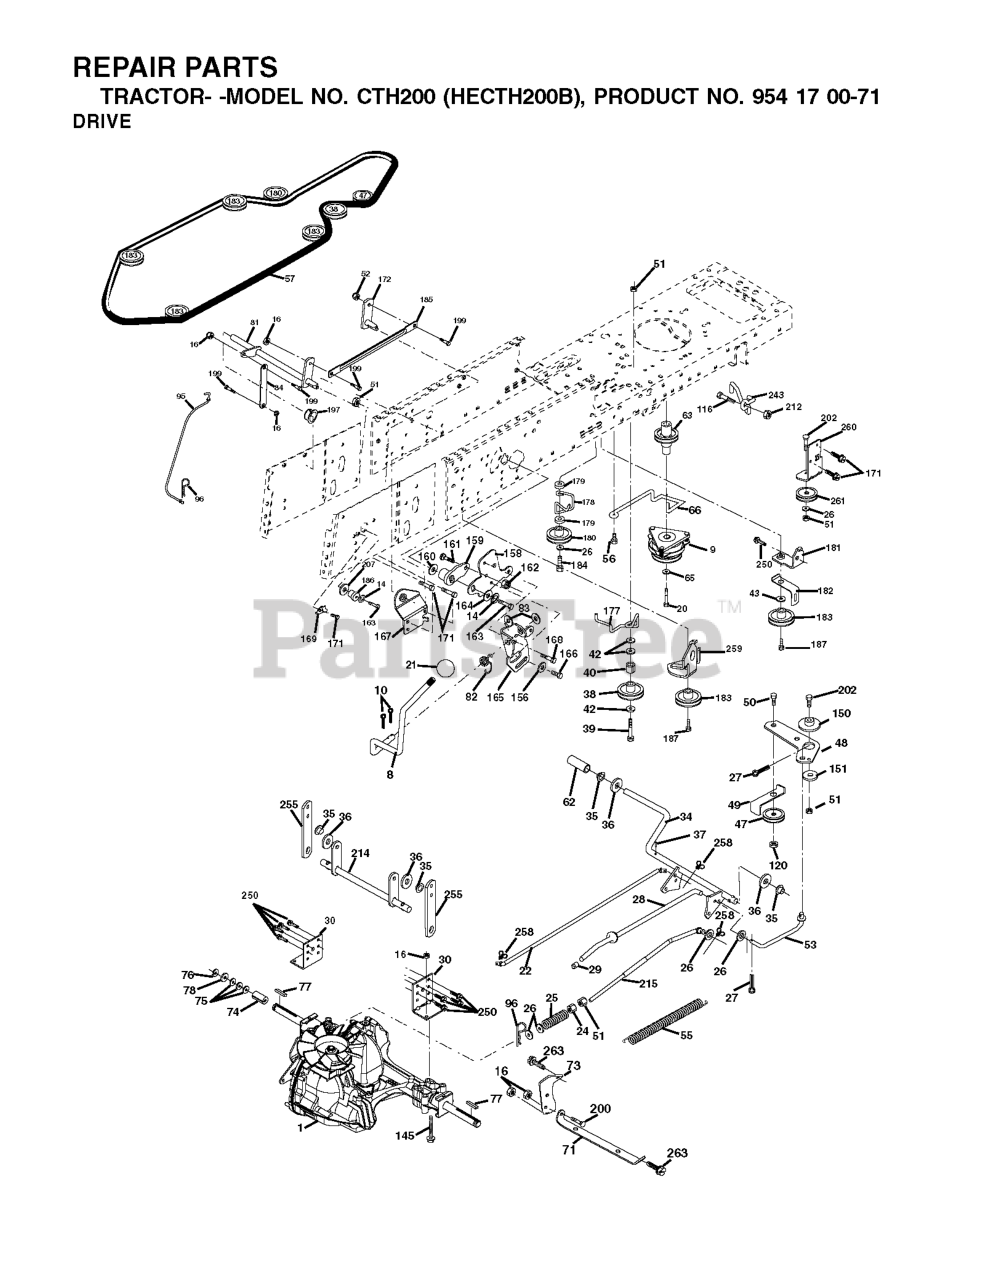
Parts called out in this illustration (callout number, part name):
8	ROD.SHIFT.FENDER.ADJ.LT.CRD
10	PIN COTTER
14	LOCKWASHER
16	NUT.71038.31-18.HEX.NYLOCK
20	BOLT
21	KNOB.DUCKHEAD.1/2
22	ROD
24	NUT
25	SPRING ROD LT
26	WASHER
27	COTTER PIN
28	ROD, PARKING BRAKE
29	PLUNGER CAP
30	BRKT, TRNSXLE MNT 20"
33	RP BOLT 5/16-18 X3/4 ZN/YEL GR
34	SHAFT, FOOT PEDAL
35	BEARING.NYLON
37	DRIVE PIN
38	PULLEY.FLAT
42	WASHER
47	IDLER PULLEY
48	BELLCRANK, CLUTCH
49	RETAIN BELT
50	BOLT
51	LOCKNUT
52	LOCKNUT
53	LINK, CLUTCH LT
55	SPRING, RETURN LT
56	SCREW.3/8-16
57	V-BELT 113"
62	COVER, PEDAL (1 2)
63	PULLEY.ENGINE.CVX.LT
65	LOCKWASHER
66	KEEPER BELT ENGINE
71	STRAP TORQUE LH HYDRO
73	STRAP TORQUE RH HYDRO
74	SPACER AXLE
77	SQUARE KEY
81	ASM.CROSS.SHAFT.REAR.CRD.0510
82	SHIFT SPRING
83	WASHER
84	LINK.PNT.TRANSAXLE.0510.CRD
95	LINK
96	RETAINER M
116	BOLT D
120	NUT LOCK FLG 3/8-16 UNC
145	BOLT HEX 5/16-18 GR 5
150	BUSHING.BELLCRANK.GRD.DR
151	WASHER 12/32X2X10GA
156	WASHER.SRRTD.5/16
158	BRACKET
159	HUB
160	Washer 29/32 x 1 - 1/4 x 16 Ga.
161	BOLT
162	NUT.CROWNLOCK.1/4
164	Washer 5/8 x .281 x 10 Ga.
165	RP BRACKET
167	BRACKET.SUPT.SHIFT.CRD
168	BOLT.SHOULDER.5/16-18X
169	PLATE.FASTENING.CROSS.SHAFT
172	LINK
177	KEEPER
178	KEEPER
180	PULLEY.FLAT.IDLER
181	BRACKET
182	BELT GUIDE
184	SCREW.HXWSH.3/8
185	LINK
186	HUB.TAPERED.ROUND.CRD
187	BOLT.5/16-18X1.25
197	NYLINER SNAP 5/8" ID
199	BOLT SHOULDER 5/16-18 UNC
207	WASHER NYL
212	NUT
214	LEVER
215	ROD
243	BRKT ASM MTNG
250	SCREW 3/8-16X3/4
255	SHAFT
258	CLIP RETAINER
259	BRACKET
261	FLAT IDLER PULLEY
263	SCREW, 3/8-16X3/4
